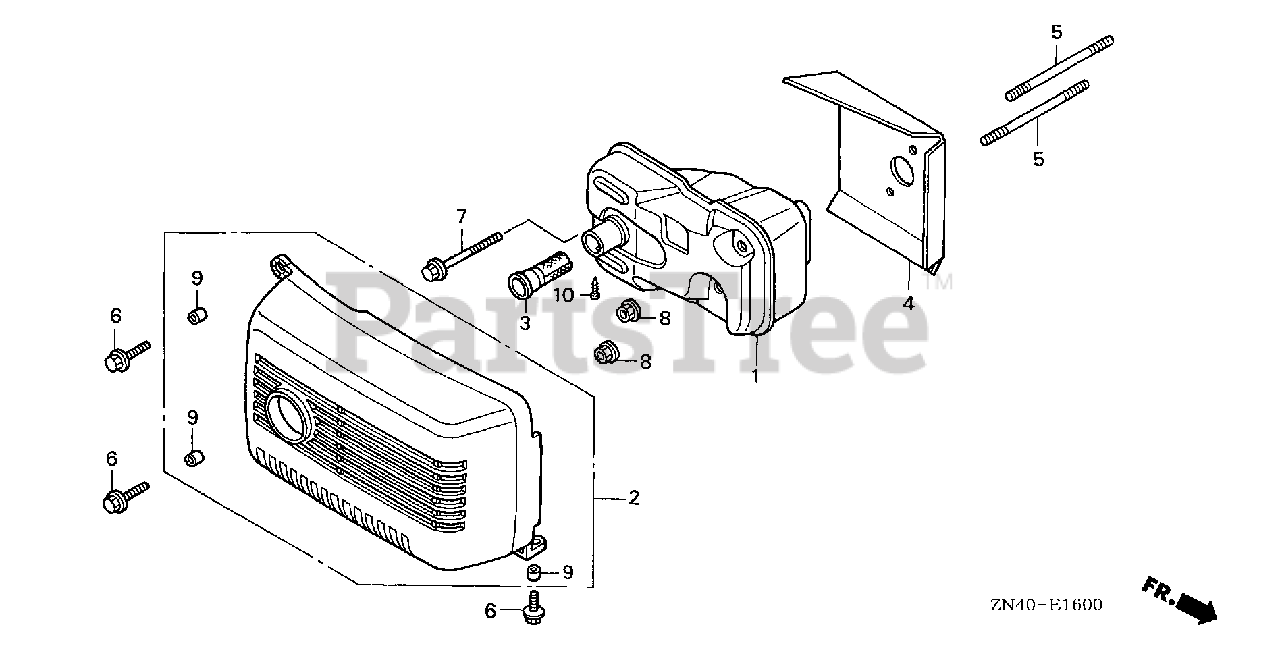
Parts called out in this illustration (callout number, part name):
1	MUFFLER
2	PROTECTOR, MUFFLER
3	ARRESTER, SPARK
4	GUIDE, AIR
5	BOLT, STUD (5X55)
6	BOLT, FLANGE (5X16)
7	BOLT, FLANGE (5X35)
8	NUT, SELF-LOCK (5MM)
9	COLLAR, TOP COVER
10	SCREW, TAPPING (4X8)
